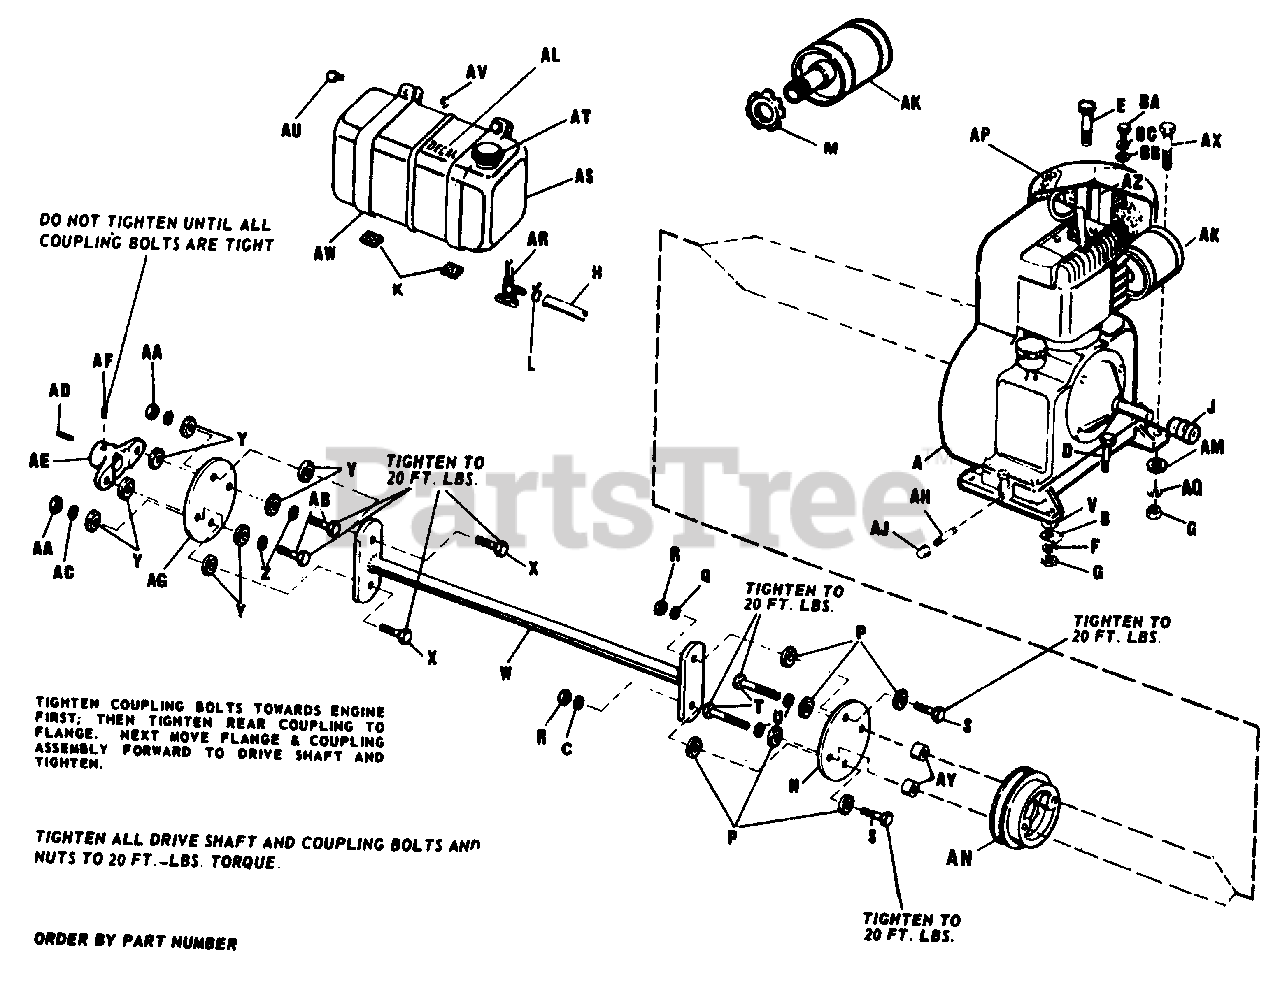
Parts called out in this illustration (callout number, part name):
A	ENGINE, Briggs & Stratton
B	Stop Axle
C	Lock Washer, 3/8"
D	Hex. Cap Screw, 3/8"-16 x 1 3/4"
E	Rect. Hd. Screw
F	Lock Washer, 3/8"
G	Full Hex. Nut, 3/8"-16
H	Fuel Hose (Flexible)
J	Crankshaft Extension Guard
L	Hose Clamp (For Service Only)
P	Special Washer
Q	Lock Washer, 3/8"
R	Full Hex. Nut, 3/8"-16
S	Hex. Cap Screw, 3/8"-16 x 1 1/4" Lg.
T	Hex. Cap Screw, 3/8"-16 x 2 1/2" Lg.
U	Lock Washer, 3/8''
V	Plain Washer, 3/8"
W	Drive Shaft Assembly
X	Hex. Cap Screw, 3/8"-16 x 1 1/4"
Y	Special Washer
Z	Lock Washer, 3/8"
AA	Full Hex. Nut, 3/8"-16
AB	Hex. Cap Screw, 3/8"-16 x 1 1/4"
AC	Lock Washer, 3/8"
AE	Drive Shaft Flange
AF	Cup Point Socket Head Set Screw, 3/8" 24 x 3/8"
AH	Pipe Nipple, 3/8" x 1" Lg.
AJ	Pipe Cap, 3/8"
AK	Exhaust Muffler
AL	Decal, Fuel Tank
AM	Plain Washer, 3/8"
AP	Film, Air Cleaner
AQ	Lock Washer, 3/8"
AR	Shut-Off Valve
AS	Fuel Tank
AT	Fuel Tank Cap
AU	Hex. Hd. Cap Screw, 1/4"-20 x 1 3/4"
AV	Full Hex. Nut, 1/4"-20
AW	Tank Strap
AX	Hex. Hd. Capscrew, 3/8"-16 x 2" Lg.
AZ	Air Cleaner Spacer
BA	Hex. Hd. Cap Screw, 1/4"-20 x 5/8"
BB	Plain Washer, 1/4"
BC	Lock Washer, 1/4"
